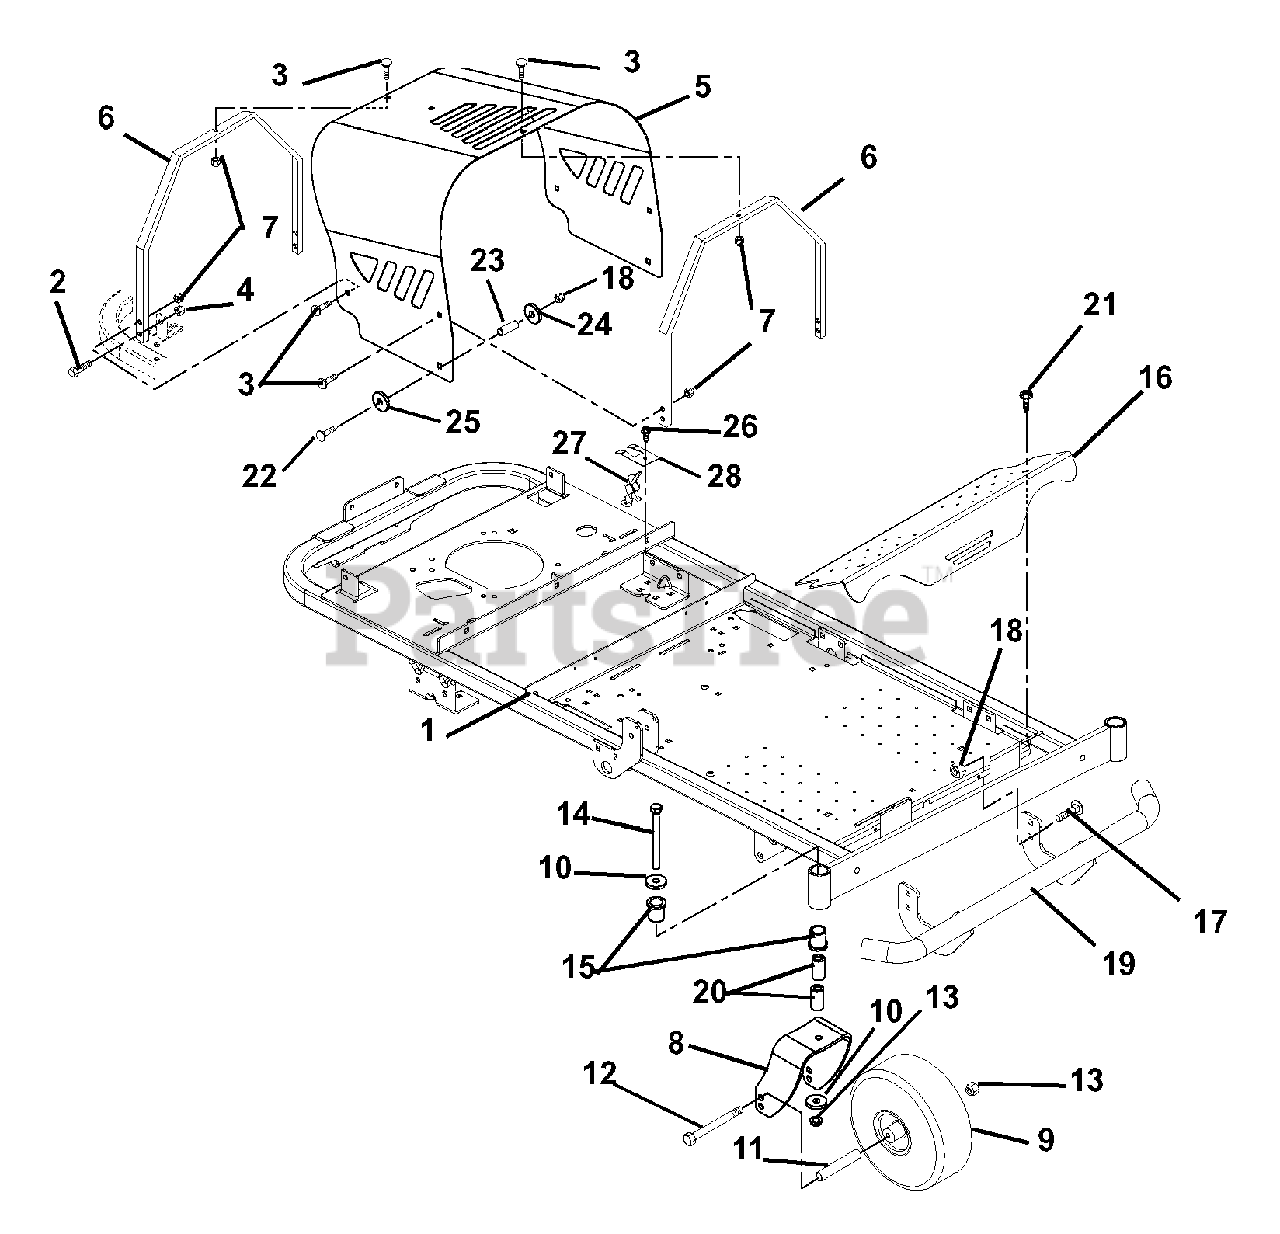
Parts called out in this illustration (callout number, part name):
1	WMT, FRAME
2	BOLT-SHLDR .375-16X.150
3	@BLT-RHDSSQNK .31-18X.62 G5YZ
4	@NUT-LK-TOP-FLG .38-16 YWZC
5	ENGINE HOOD
6	BRACE, HOOD
7	@NUT-LK-TOP-FLG .31-18 YWZC
8	FORK,CASTER
9	ASSY-TIRE 4 X 11 - 4 PLY
10	WSHR-FL-STL.511X1.441X.125 YWZ
11	SPACER, ROLLED WHEEL
12	@BLT-HEX .50-13X6.50 GR5 YWZC
13	@NUT-LK-TOP-FLG .50-13 YWZC
14	@BLT-HEX .50-13X5.00 GR5 YWZC
15	BSHG-FLG 1.00X1.25X1.50X1.50EP
16	FOOT REST
17	@BLT-RDHDSQNK .38-16X1.00 G5YZ
18	@NUT-LK-NYL-FLG .38-16 YWZC
19	BUMPER-ZOOM
20	SPACER, CASTER .50X1.00X1.84
21	@SCR-TAP .31-18X.50 HWH TR YWZ
22	@BLT-RDHDSQNK .38-16X2.50 G5YZ
23	BSHG, SPCR .390X.625X1.25 PM
24	WSHR-FL-STL .375X1.125X.065YWZ
25	@WSHR-FL-STL.531X1.06X.095YWZC
26	@SCR-TAP .25-20X.50 HWH TR YWZ
27	HOOD CLIP
28	BRACKET, HOOD CLIP
